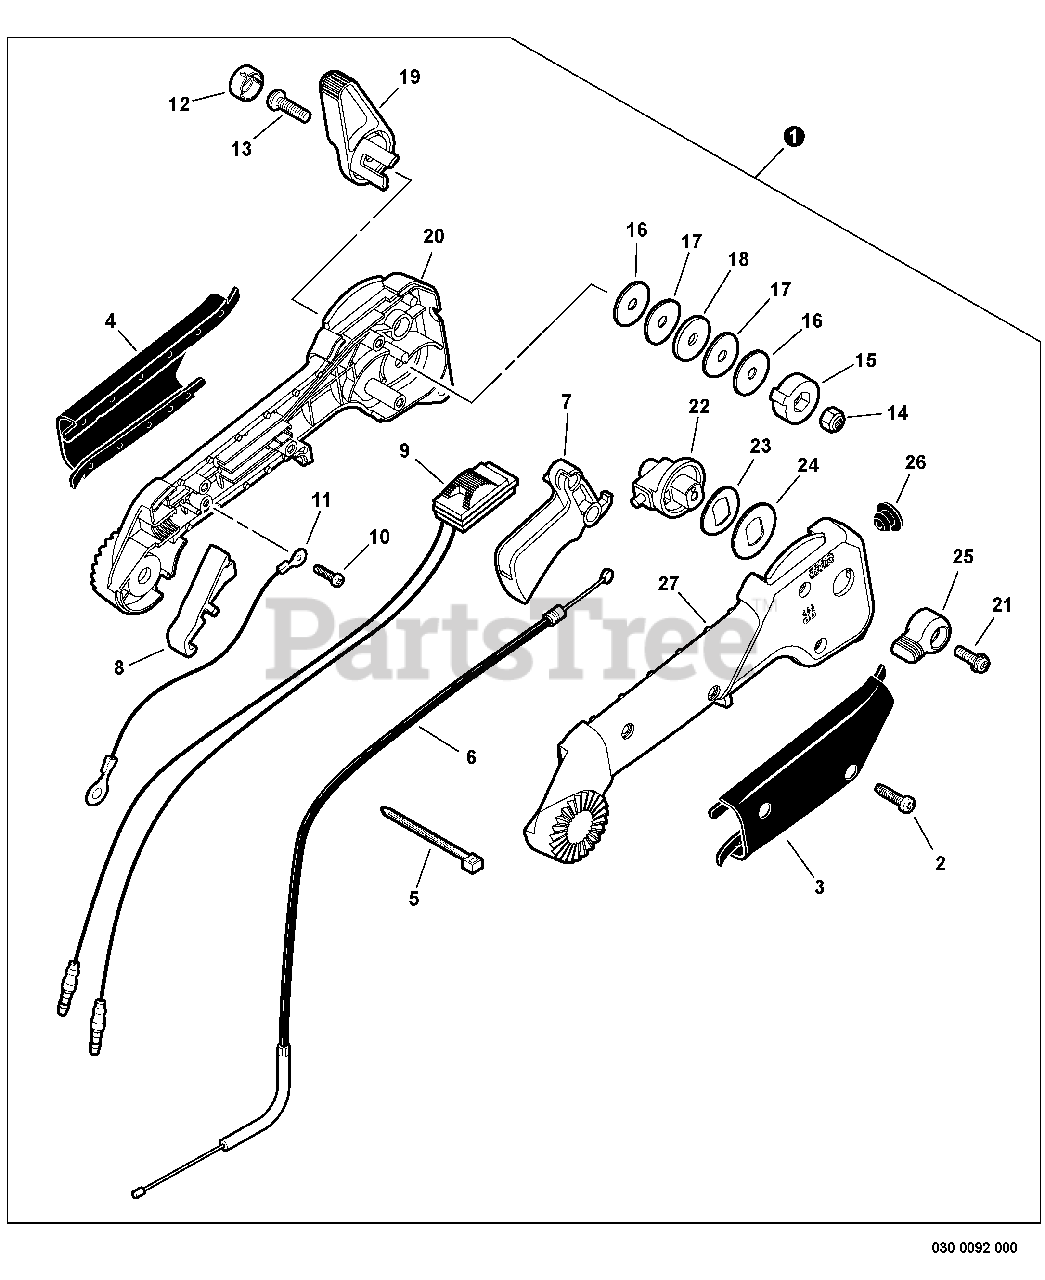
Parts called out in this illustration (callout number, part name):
1	THROTTLE CONTROL ASSY
2	SCREW M4×16
3	GRIP, RIGHT
4	GRIP, LEFT
6	CABLE, THROTTLE
7	TRIGGER, THROTTLE
8	COVER, HANDLE REAR
9	SWITCH, ON-OFF
10	SCREW M3×8
11	LEAD - GROUND
12	CAP, BOLT
13	BOLT M6×25
14	NUT, NYLON M6
15	LEVER, THROTTLE
16	WASHER M6
17	WASHER, SPRING
18	WASHER M6
19	CONTROL, THROTTLE
20	CONTROL HANDLE - LEFT
21	SCREW M4×16
22	LIMITER ASSY, THROTTLE
23	WASHER, WAVE
25	LEVER, THROTTLE LIMITER
26	PLUG, THROTTLE LIMITER
27	CONTROL HANDLE - RIGHT
